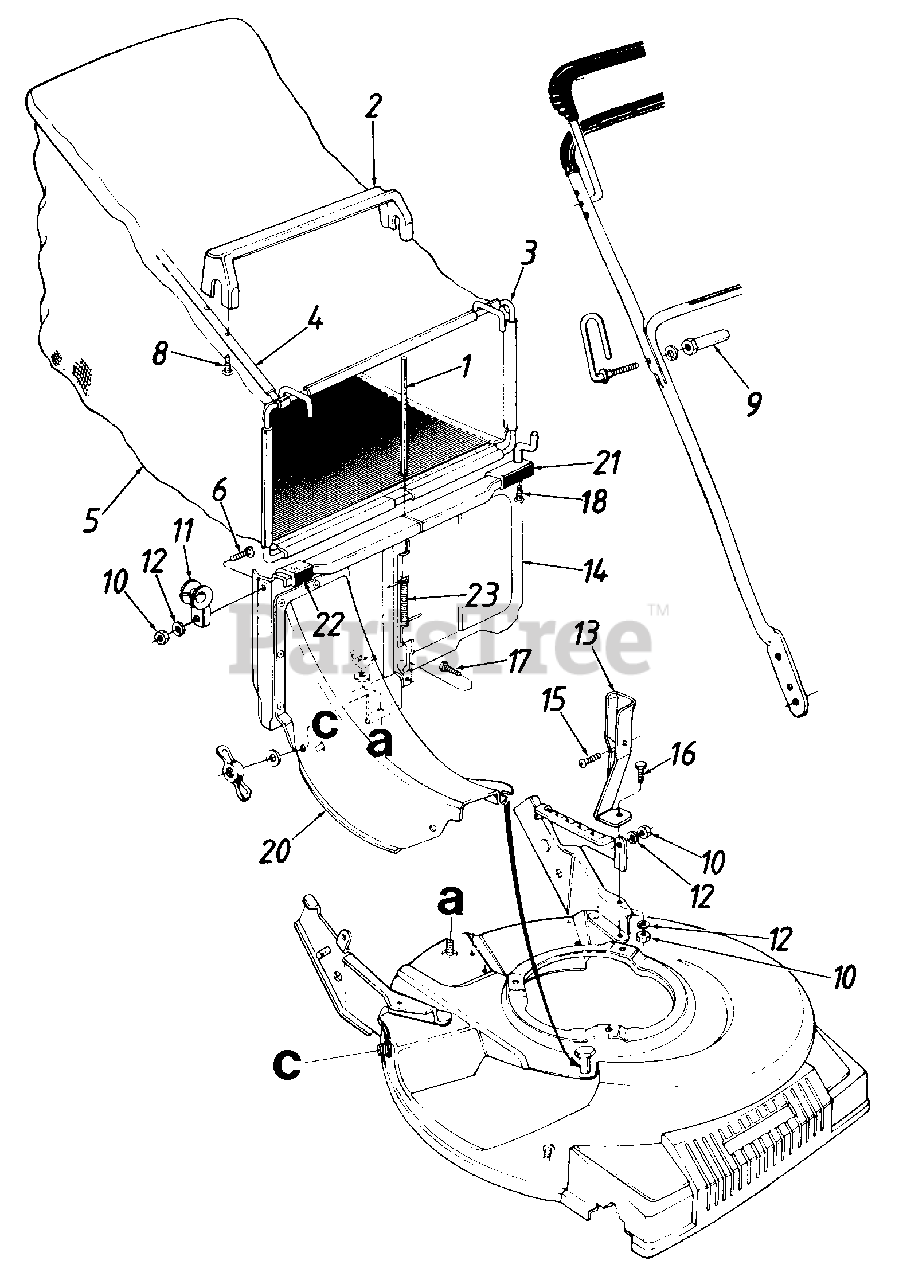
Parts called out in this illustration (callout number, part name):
1	Chute Rod
2	Bag Handle
3	Front Frame Ass'y.
6	Truss Mach. Scr. 1/4-20 x .75"
8	Truss Mach. Tap Scr.
9	Catcher Support Pin
10	Hex Nut 1/4-20 Thd.
11	Rope Guide
12	L-Wash. 1/4" I.D.
13	Grass Catcher Bracket
14	Chute Door
15	Truss Mach. Scr. 1/4-20 x .5'
16	Hex Bolt 1/4-20 x .5" Lg.
17	Hex B-Tap Scr. #10 x .38"
18	Hex AB-Tap Scr. 1/4 X .75"
20	Top Discharge Chute Ass'y.
21	Door Clip
22	Panel Clip
23	Torsion Spring
